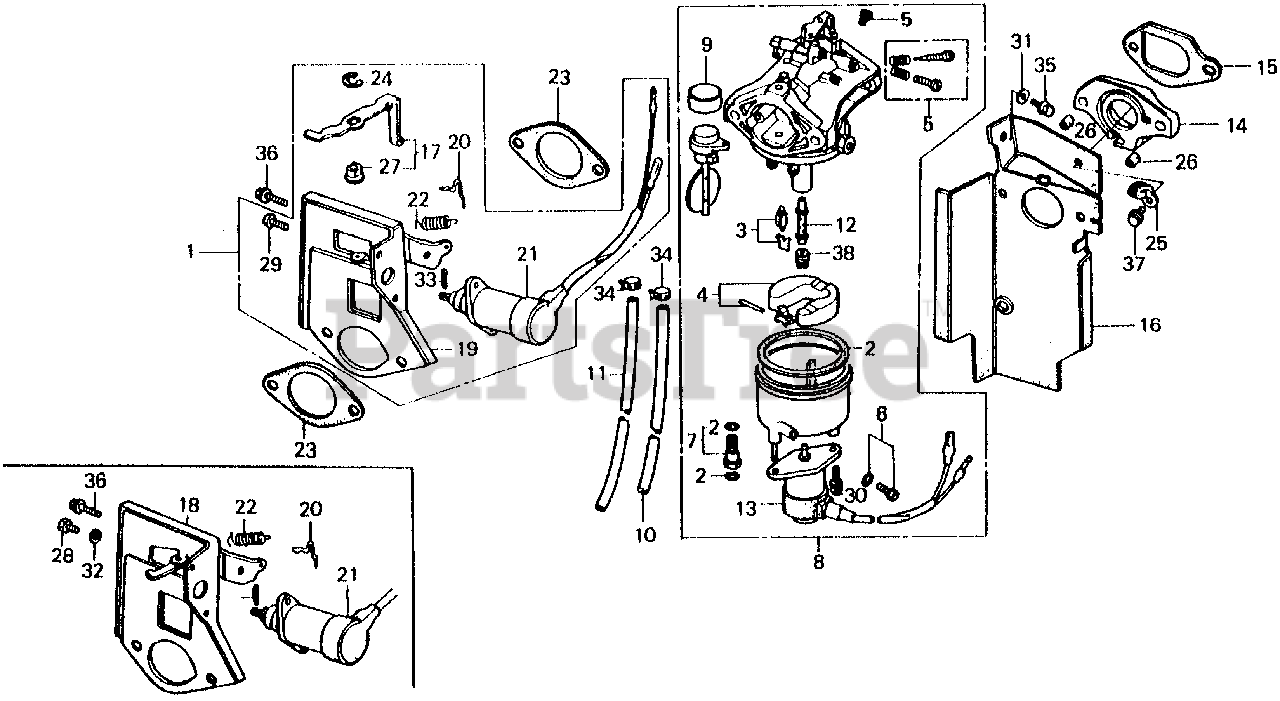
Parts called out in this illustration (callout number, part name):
1	STAY SET, SOLENOID
2	GASKET SET
3	VALVE SET, FLOAT
4	FLOAT SET
5	SCREW SET A
6	SCREW SET, DRAIN
7	SCREW SET B
8	CARBURETOR ASSY. (BB39A A) (NOT AVAILABLE)
8	CARBURETOR ASSY. (BB35A B/C) (NOT AVAILABLE)
8	CARBURETOR ASSY. (BB39A C/D) (NOT AVAILABLE)
8	CARBURETOR ASSY. (BB39A E) (NOT AVAILABLE)
9	CAP, CHOKE LEVER DUST
10	TUBE, DRAIN
11	TUBE, OVERFLOW
12	NOZZLE, MAIN (NOT AVAILABLE)
13	VALVE ASSY., SOLENOID
14	INSULATOR, CARBURETOR
15	GASKET, INSULATOR
16	GASKET, CARBURETOR
17	LEVER, SOLENOID CHOKE
18	STAY SET, SOLENOID
18	STAY, SOLENOID
19	STAY, SOLENOID
20	ROD, CHOKE
21	CHOKE, SOLENOID (N/A: USE ALTERNATE P/N 06162-ZA0-315)
21	CHOKE, SOLENOID (NA USE ALT:06162-ZA0-315)
22	SPRING, CHOKE RETURN
23	GASKET, AIR CLEANER
24	E-RING (4MM)
25	CLIP, WIRE HARNESS
26	COLLAR, STUD BOLT (NOT AVAILABLE)
27	BUSH, CHOKE LEVER
28	BOLT, HEX. (5X8)
29	SCREW, PAN (5X8)
30	SCREW-WASHER (5X12)
31	WASHER, PLAIN (6MM)
32	WASHER, SPRING (5MM)
33	PIN, COTTER (1.6X10)
34	CLIP, TUBE (D10)
35	BOLT, FLANGE (6X10)
36	BOLT, FLANGE (6X12)
37	BOLT, FLANGE (8X16)
38	JET, MAIN (#90)
38	JET, MAIN (#92)
38	JET, MAIN (#95)
NI	CHAMBER SET, FLOAT
